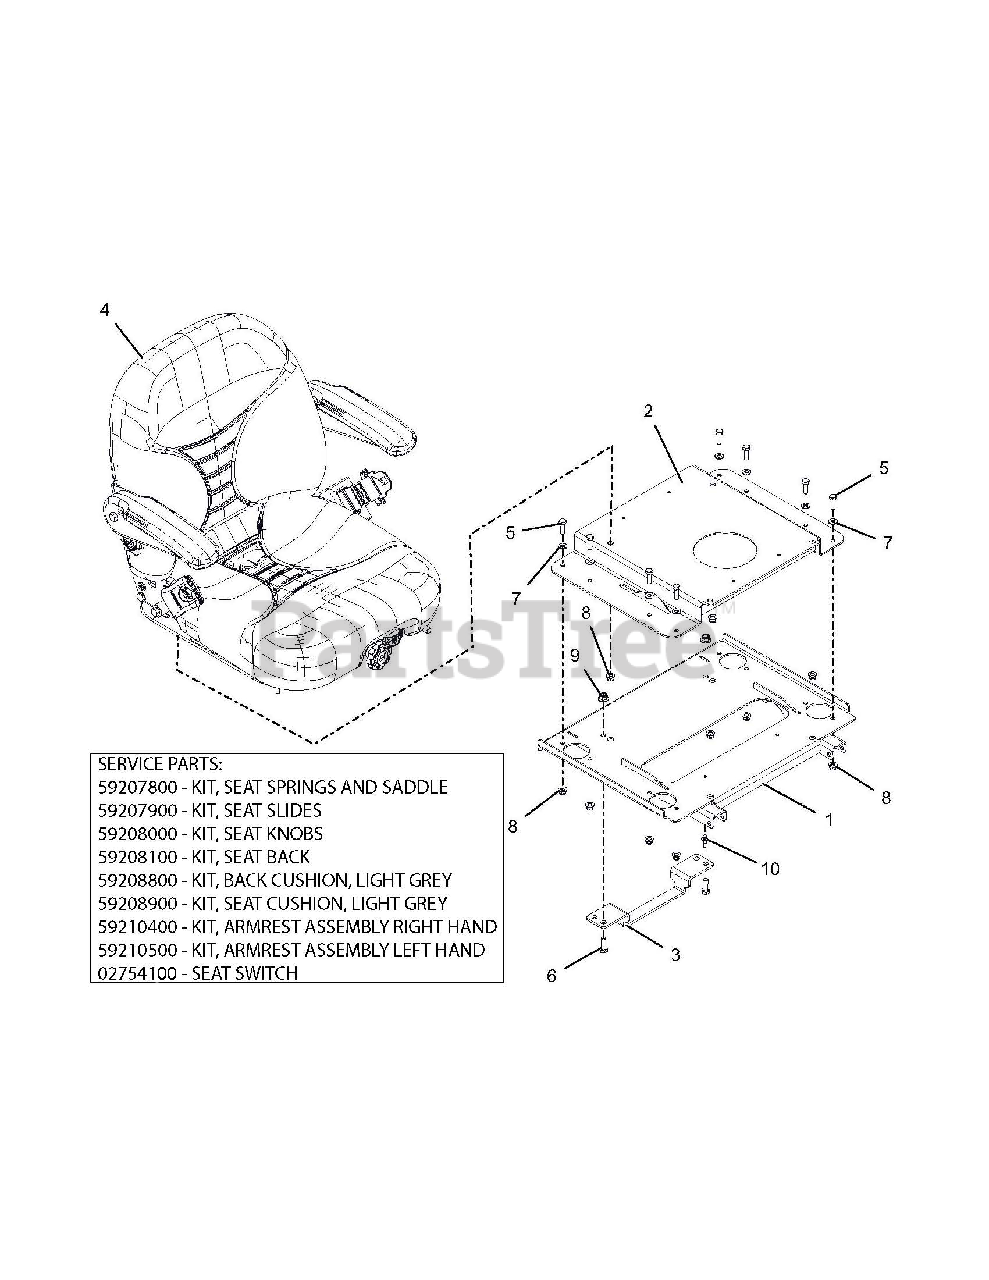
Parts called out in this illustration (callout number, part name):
1	SEAT ISO MTG WMT W/SAFETY DECALS
2	WLDMT, SEAT BASE MOUNTING-RED
3	BRKT, SEAT LATCH-BLACK
4	SEAT, SUSPENSION W/SEAT BELT, LT GRAY
4	KIT, SEAT SPRINGS AND SADDLE
4	KIT, SEAT SLIDES
4	KIT, SEAT KNOBS
4	KIT, SEAT BACK
4	KIT, BACK CUSHION, LIGHT GREY
4	KIT, SEAT CUSHION, LIGHT GREY
4	KIT, ARMREST ASSEMBLY RIGHT HAND
4	KIT, ARMREST ASSEMBLY LEFT HAND
4	SEAT SWITCH
5	BLT-HEX .31-18X1.00 GR5 YWZC
6	BLT-HEX .38-16X1.00 GR5 YWZC
7	WSHR-FL-STL.344X.688X.065YWZC
8	NUT-LK-NYL-FLG .31-18 YWZC
9	NUT-LK-NYL-FLG .38-16 YWZC
10	CABLE TIE W/ TREE
